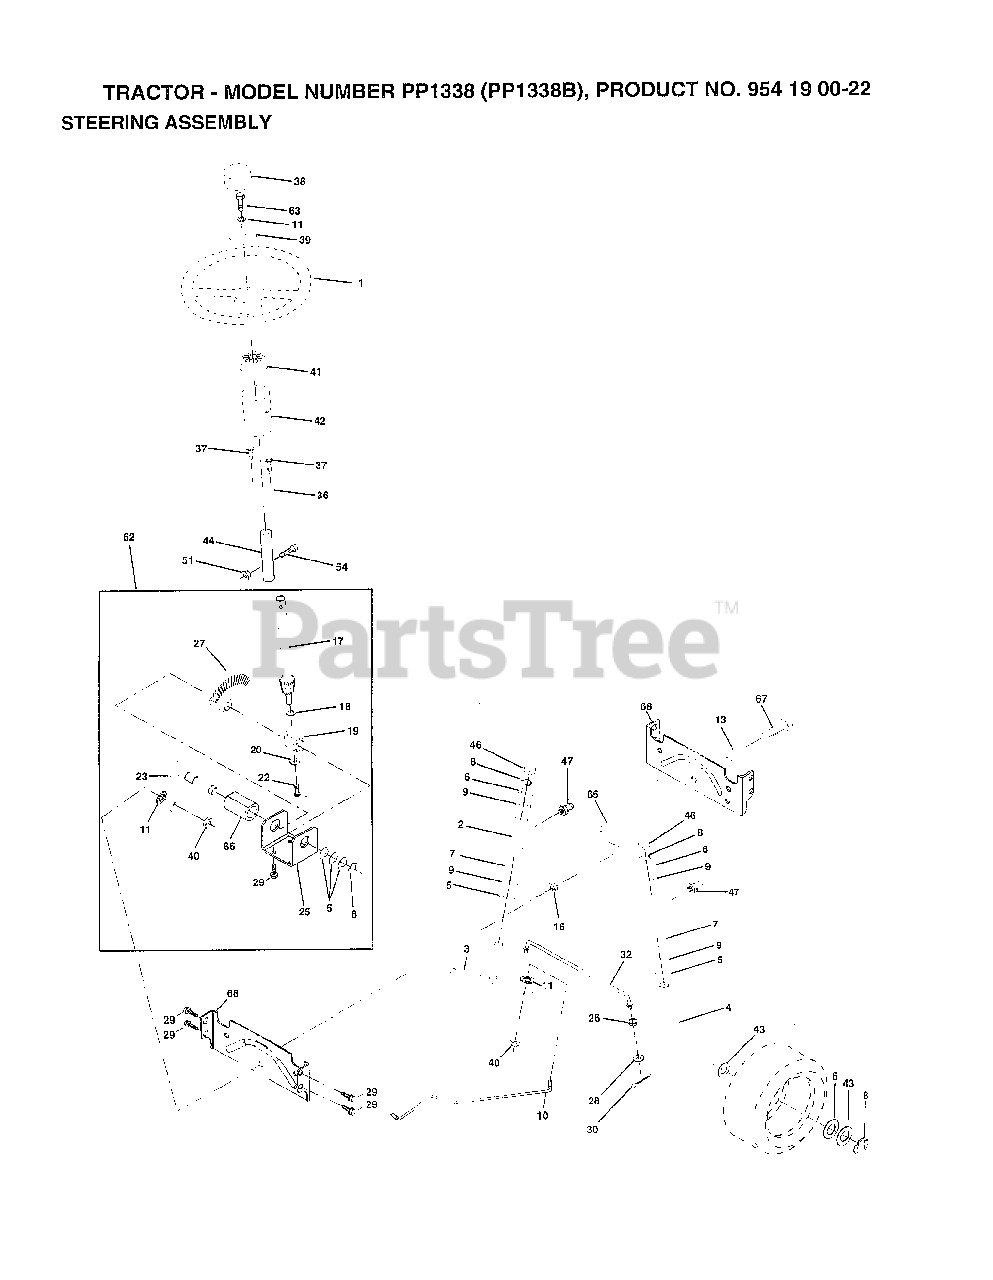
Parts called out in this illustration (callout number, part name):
2	AXLE ASM
3	SPINDLE.ASM.LH
4	"SPINDLE ASM,RH"
5	WASHER .T
6	WASHER
7	WASHER
8	RING
9	COL. SRTG. BEAR.
10	DRAGLINK-STAMPED
11	LOCKWASHER
13	BEARING AXLE
15	"NUT-LOC,FLANGE LT"
17	SHAFT ASM STEERIN
18	THRUST WASHER
19	SUPPORT.SHAFT
22	SCREW HEX SOC1/4-
25	BRKT-STEERING
26	BUSHING.DRAGLINK
27	GEAR SECTOR
28	WASHER
29	SCREW
30	COTTER PIN
32	TIE ROD
36	BUSHING.STEERING
37	"SCREW-TT,10-32 FL"
38	"INSERT,STR WHEEL"
39	WASHER T
40	GRIPCO NUT
41	ADAPTER LT
42	BOOT.STEER.PL
44	EXT SHAFT STEERIN
46	CAP
47	ZERK M
51	NUT
54	BOLT
62	KIT STEERING ASM
63	BOLT
65	SPACER AXLE
66	"BEARING-ARM,PITMA"
67	BOLT
68	BRACE AXLE
